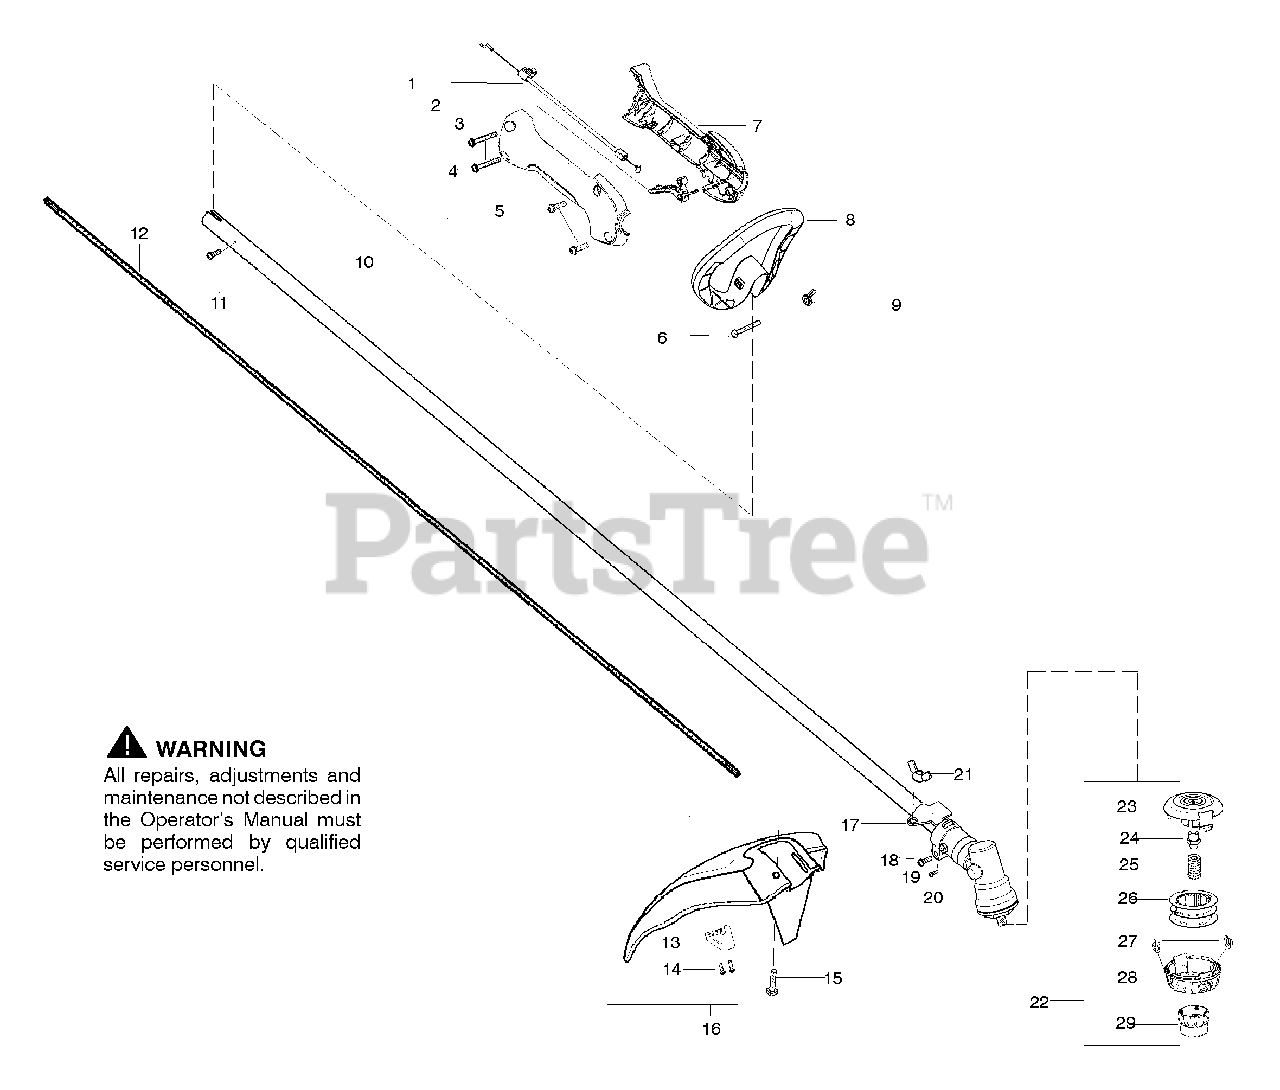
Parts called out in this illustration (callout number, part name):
1	Assy-Throttle Cable
3	Throttle Hsg. (Right)
6	Bolt-Handle
7	Throttle Hsg. (Left)
8	Assy-Handle
9	Wingnut-Handle
10	Assy-Drive Shaft Hsg.
11	Screw
12	Shaft-Flex
13	Line Limiter
15	Bolt-Shield
16	Kit-Shield Assy
17	Bracket-Shield
20	Assy-Gearbox
21	Wingnut
22	Assy-TNG 7 Head
26	Accy-Wound Spool
27	Eyelet
28	Cover
